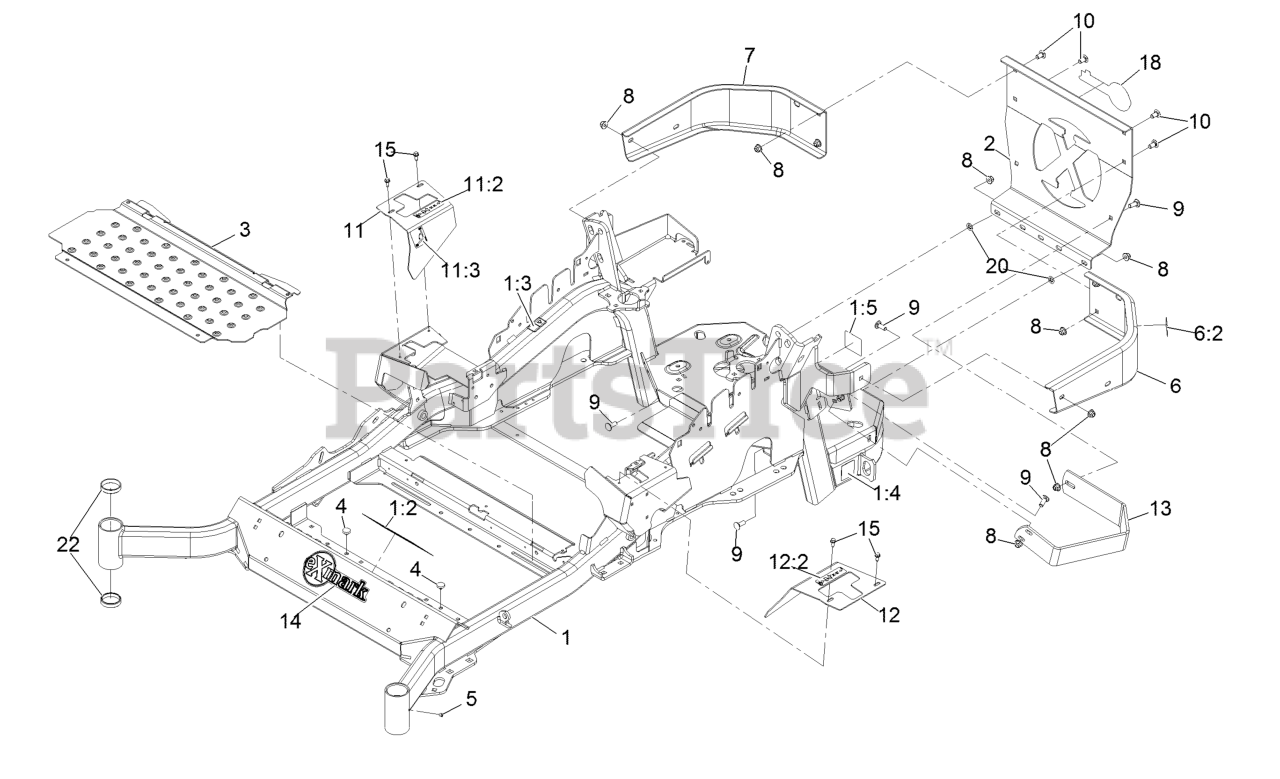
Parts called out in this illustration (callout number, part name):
1	Mainframe ASM
1:2	Decal-Danger
1:3	Decal-Warning
1:4	Decal-Hazard, Pinched Finger
1:5	Decal-Spark Arrester
2	Plate,Rear Guard
6	LH Bumper ASM
6:2	Decal-Warning
7	Bumper-RH
8	Nut-Nyloc 3/8-16 Flg
9	Bolt-Carriage 3/8-16 X 1
10	Bolt-Carriage 3/8-16 X 3/4
11	RH Motion Control Cover ASM
11:2	Decal-Control, Motion
11:3	Decal-Park Brake, CE
12	LH Motion Control Cover ASM
12:2	Decal-Control, Motion
13	Guard-Muffler
14	Decal-Exmark
15	Screw-HWH 1/4-20 X .62
18	Decal-Exmark Logo
20	Nut-Push 3/8-16
22	Cup-Bearing Tapered Roller
